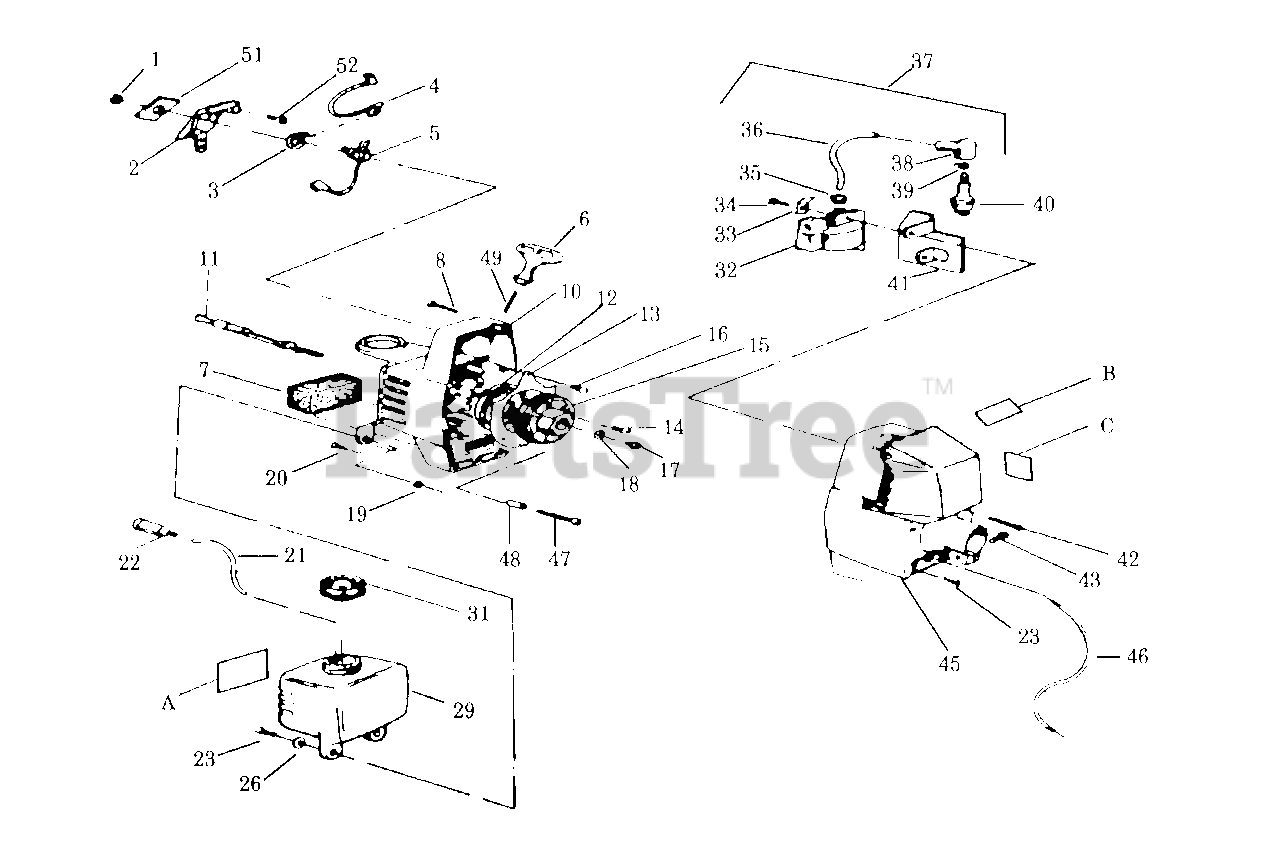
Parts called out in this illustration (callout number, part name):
1	Grounding Switch Nut
2	Housing Switch
3	Grounding Switch Washer
4	Lead Wire Grouding Switch
5	Grounding Switch Kit (Inc. 1,3,4,33)
6	Handle
7	Air Filter
10	Fan Housing Kit
11	Choke Knob
12	Starter Pulley Spring
13	Air Baffle
15	Starter Pulley
17	Screw
21	Line Kit
22	XR-105-T 1
22	XR-105-T 2; XR-125-T 1
26	Lockwasher
29	Fuel Tank Ass'y.
31	Fuel Cap Ass'y.
32	Ignition Module Kit
33	Electrical Tab
34	Screw
35	Plug Wire Grommet
36	High Tension Lead Wire
37	High Tension Lead Ass'y. (Inc.36,38,39)
38	Spark Plug Boot
39	Spark Plug Lead Connector
40	Spark Plug (CJ-14)
41	Air Deflector
46	Throttle Cable
49	Rope Kit
51	Indicating Switch Plate
A	Fuel Tank Decal
B	XR-105 & XR-125 (Not a serviceable part)
C	XR-125 Right
C	XR-125 Only
